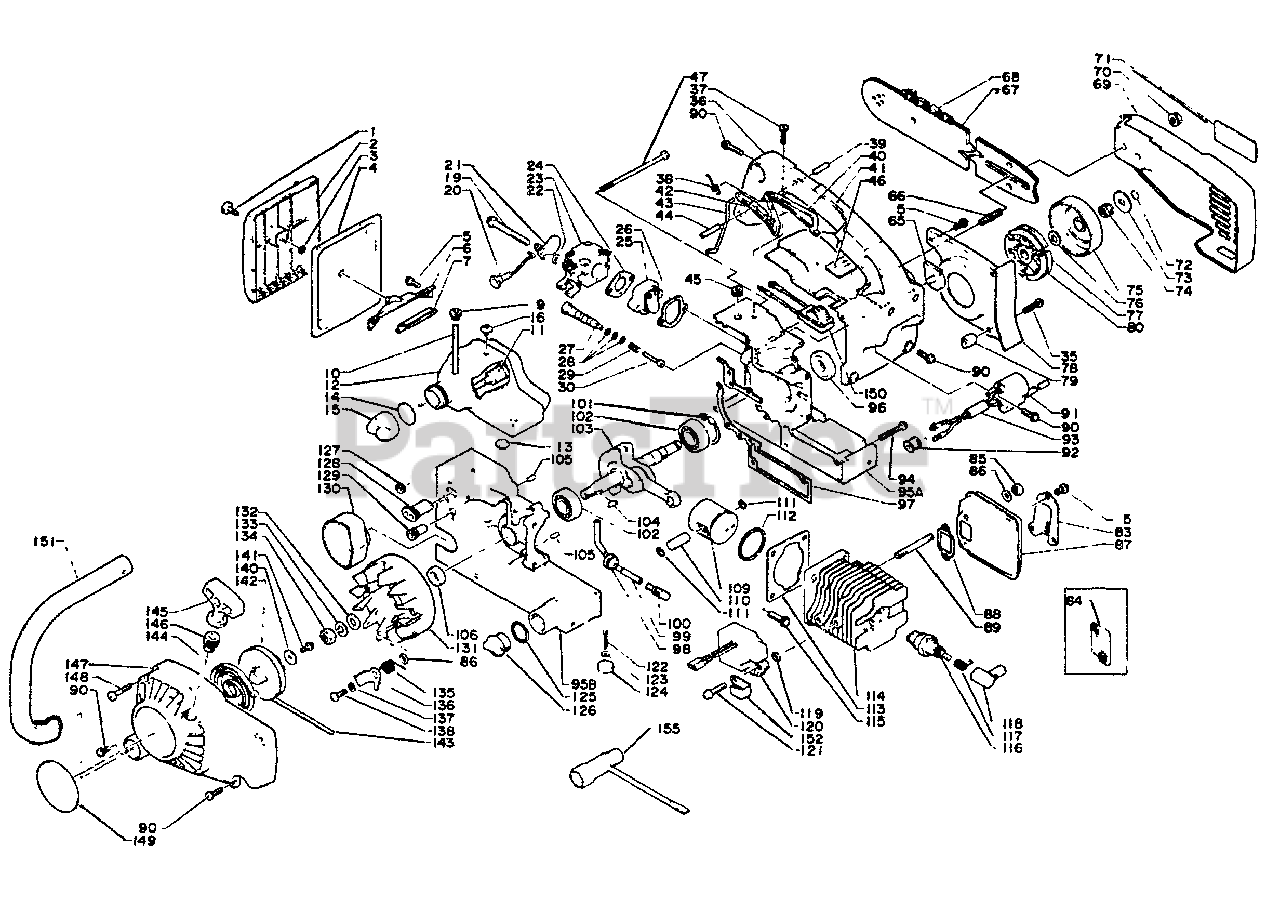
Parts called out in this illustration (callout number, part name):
1	THUMBSCREW
2	COVER, AIR FILTER
3	RING, RETAINING - 3
4	FILTER, AIR
5	SCREW - 4X10
6	BRACKET, AIR CLEANER
7	CUSHION
9	GROMMET
10	FUEL PIPE KIT
11	FILTER, FUEL
12	TANK, FUEL
14	GASKET, CAP
15	CAP
19	SCREW - 5X55
20	ROD, CHOKE
21	SHUTTER, CHOKE
22	WASHER
23	CARBURETOR
24	GASKET, INTAKE
25	INSULATOR
26	GASKET, INTAKE
27	AUTO-OILER ASSY
28	O-RING - 5
30	AUTO-OILER ASSY
35	SCREW - 4X20
36	HANDLE - TOP
37	SCREW - 4X18
38	SPRING
39	PIN - SPRING -- 5X18
40	LOCKOUT, THROTTLE
41	GRIP, HANDLE
42	TRIGGER, THROTTLE
43	ROD, THROTTLE
44	PIN - SPRING -- 5X25
46	LABEL
65	PLUG
66	STUD, GUIDE BAR
67	GUIDE BAR
68	CHAIN, SAW
69	GUARD, SPROCKET
70	NUT - 6 -- FLANGE
71	LABEL - ECHO
72	RING, RETAINING
73	WASHER
74	BEARING, NEEDLE
75	DRUM, CLUTCH
76	WASHER, CLUTCH
77	CLUTCH ASSY
78	PLATE, SEAL
79	SPACER
80	SPRING, CLUTCH
83	GUIDE, EXHAUST
84	SCREEN, SPARK ARRESTOR
85	LOCKNUT - 5
86	WASHER - 5
87	MUFFLER
88	GASKET, EXHAUST
90	SCREW - 4X16
91	COIL, IGNITION
94	SCREW - 4X30
95	CRANKCASE KIT
95A	CRANKCASE KIT
95B	CRANKCASE KIT
96	SEAL, OIL
97	GASKET, CRANKCASE
98	GROMMET
99	PIPE - OIL
100	FILTER, OIL
101	RING, RETAINING - 32
102	BEARING, BALL - 6201
103	CRANKSHAFT ASSY
105	PIN - LOCATING
106	SEAL, OIL
109	PISTON KIT
110	PIN, PISTON
111	RING, RETAINING
112	RING, PISTON
113	GASKET, CYLINDER
114	CYLINDER
115	SCREW - 5X20
116	SPARK PLUG -- BPM-6A
117	TERMINAL, SPARK PLUG CAP
118	CAP, SPARK PLUG
119	SPACER
120	COIL, IGNITION
121	SCREW - 5X22
122	PIN, SPLIT -- 2X15
123	WASHER - 2
124	SEAL, FELT
125	O-RING - 16
126	CAP, OIL TANK
128	GROMMET
129	GROMMET
130	SEAL
131	FLYWHEEL
132	WASHER - 8
133	LOCKWASHER - 8
135	SPRING, RETURN
136	PAWL, STARTER
138	SCREW
141	SCREW - 4X10
142	REEL, ROPE
143	ROPE, STARTER - 3X850
144	SPRING, REWIND
145	GRIP, STARTER
146	GUIDE, ROPE
147	CASE, STARTER
148	SCREW - 4X25
149	LABEL - ECHO
150	IGNITION SWITCH ASSY
151	HANDLE - FRONT
152	CLAMP
155	T-WRENCH
